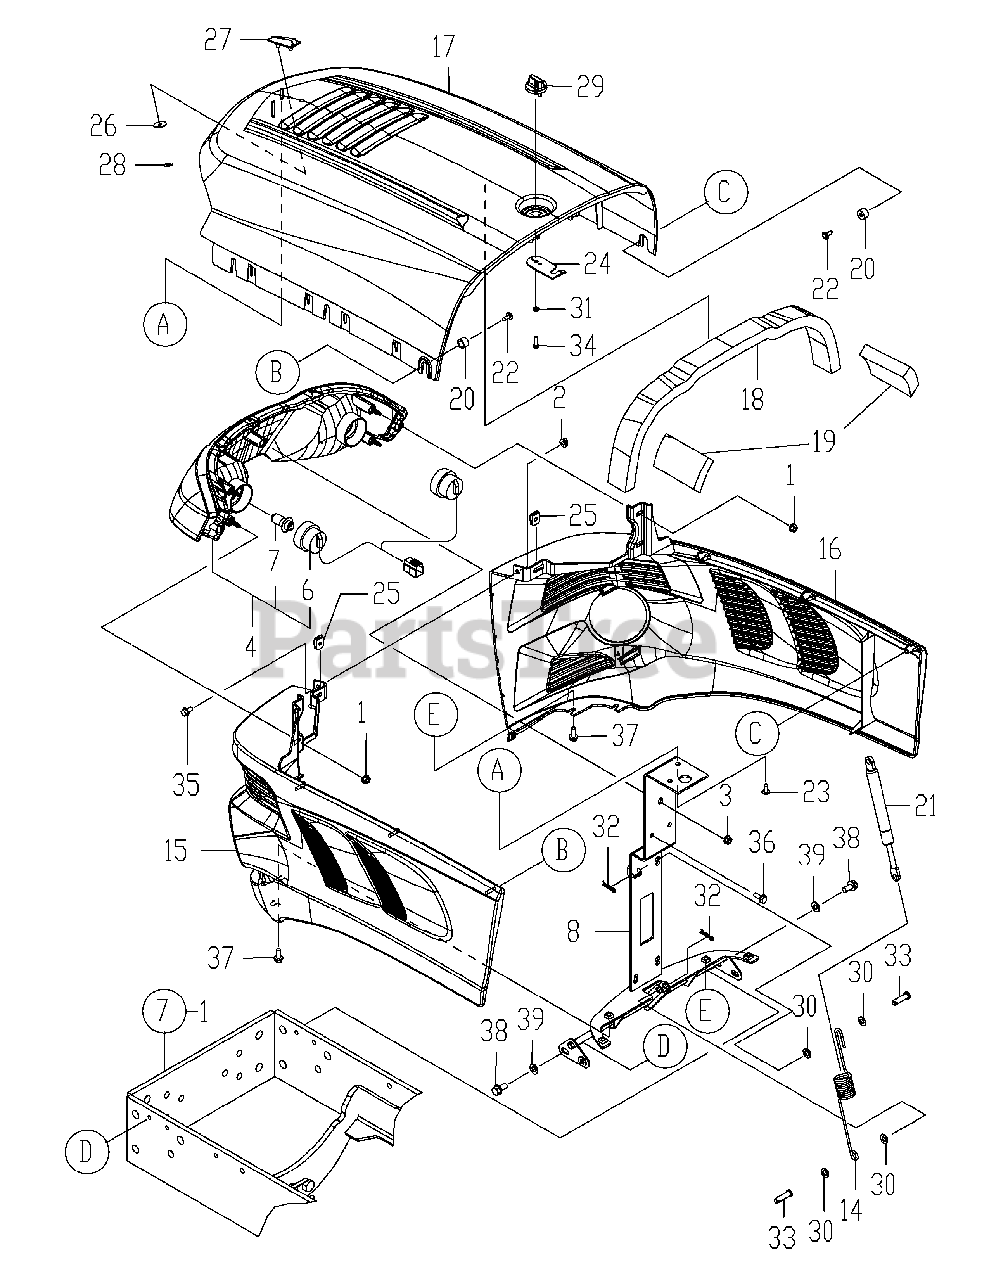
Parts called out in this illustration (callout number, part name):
4	LAMP ASSY, HEAD
6	WIRE, LEAD HEAD LAMP
7	BULB, HALOGEN 12V30/30
8	HINGE CMP, HOOD
14	SPRING, HOOD HINGE
15	HOOD, LOWER LH
16	HOOD, LOWER RH
17	HOOD, UPPER
18	SEAL, HOOD UPPER
19	CUSHION, HOOD REAR
20	COLLAR, 10X15X10
24	STOPPER (HOOD)
34	SCREW, 5.0 X 16
39	WASHER 8, POLISHED
